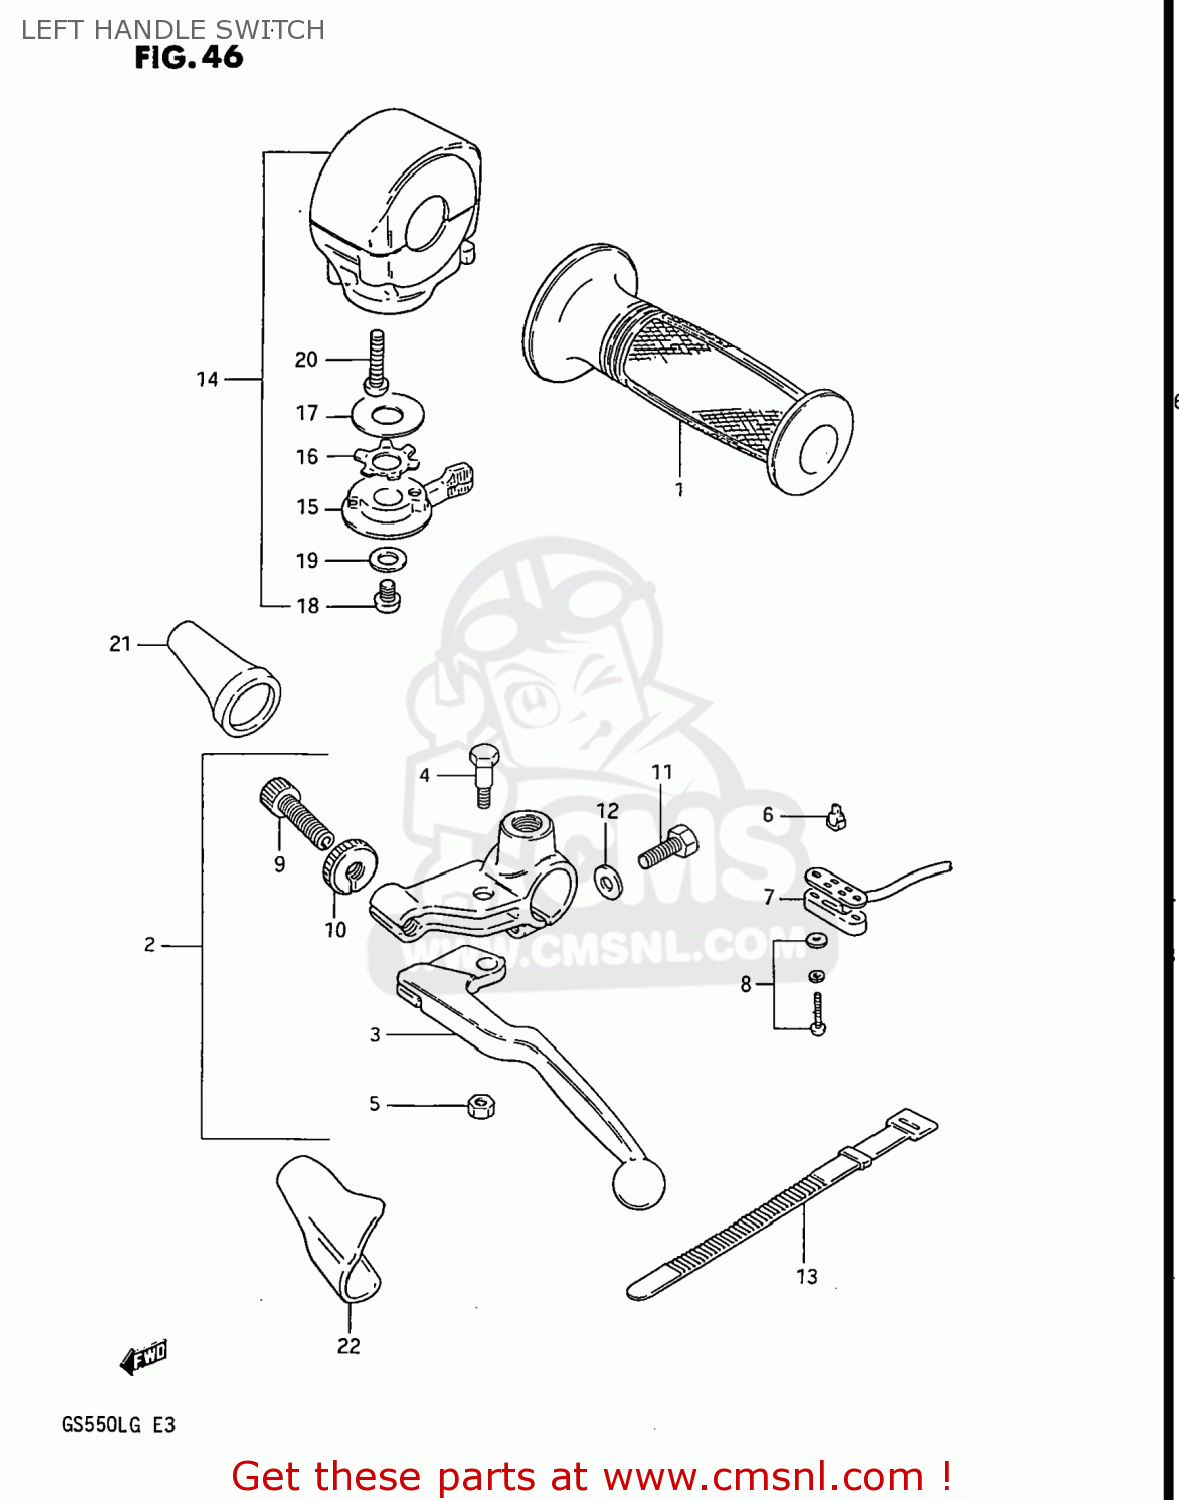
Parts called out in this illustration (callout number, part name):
1	GRIP
2	LEVER ASSEMBLY
3	LEVER,CLUTCH
4	BOLT,LEVER PIVOT
5	NUT
6	CONTACT,SWITCH
7	COVER,FR BK TERMINAL BASE
8	SCREW
9	ADJUSTER,CABLE
10	NUT,CABLE ADJUSTER
11	BOLT
12	WASHER
13	CLAMP(L:120)
14	SWITCH ASSEMBLY,HANDLE,LEFT
15	LEVER,STARTER
16	WASHER
17	WASHER
18	SCREW
19	WASHER 6MM
20	SCREW
21	BOOT,CLUTCH CABLE
22	COVER,CLUTCH LEVER
